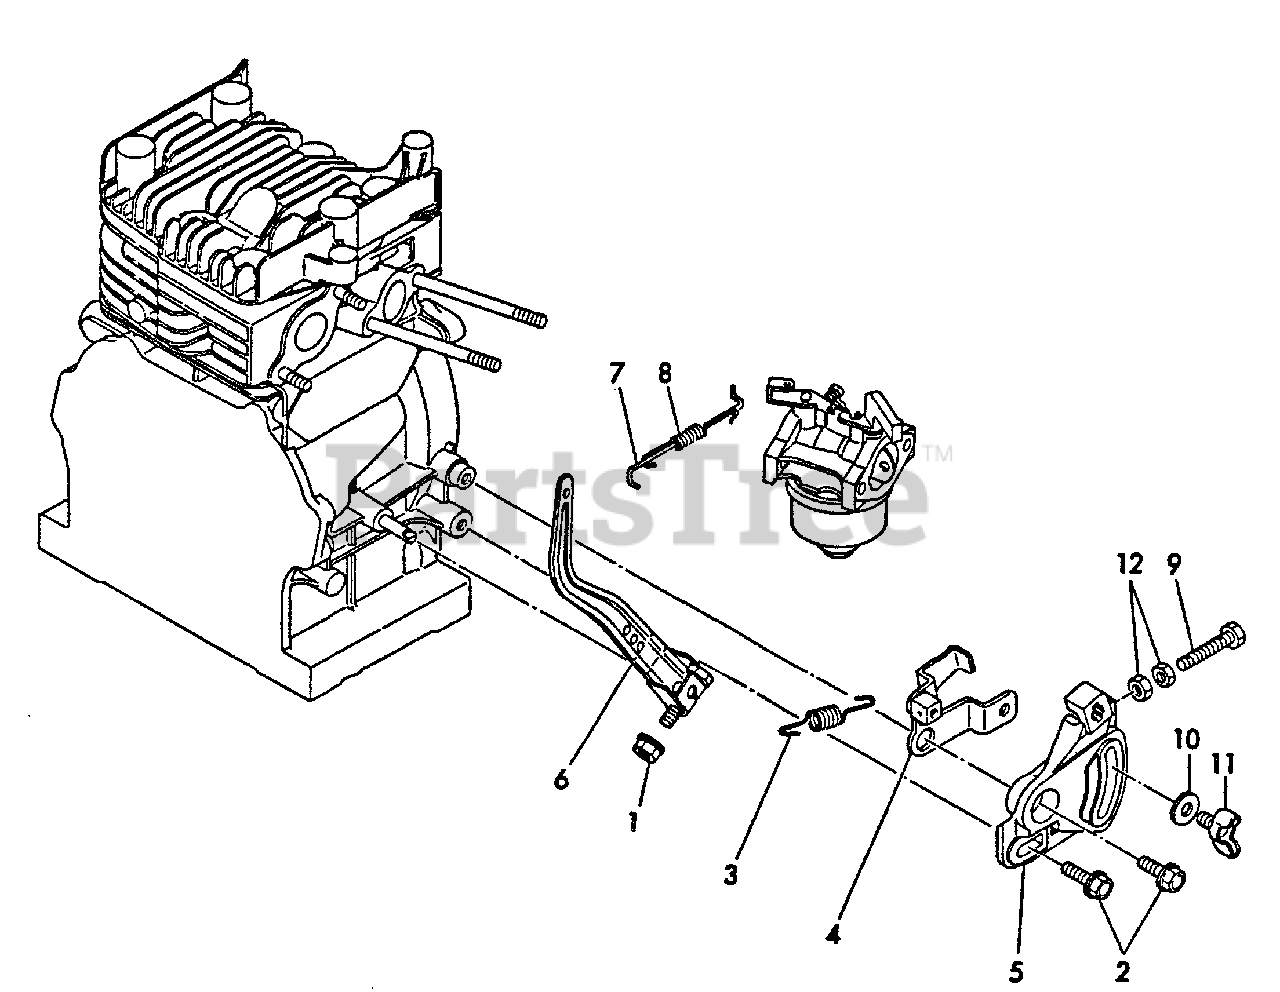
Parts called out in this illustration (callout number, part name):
1	U-NUT M6
2	BOLT - 6×20
3	SPRING, REGULATOR
4	HANDLE, REGULATOR
5	BRACKET, REGULATOR
6	LEVER, GOVERNOR
7	LINK, THROTTLE
8	SPRING, TENSION
9	BOLT
10	WASHER
11	THUMBSCREW - 6×15
12	LOCKNUT - 6 -- PLATED
